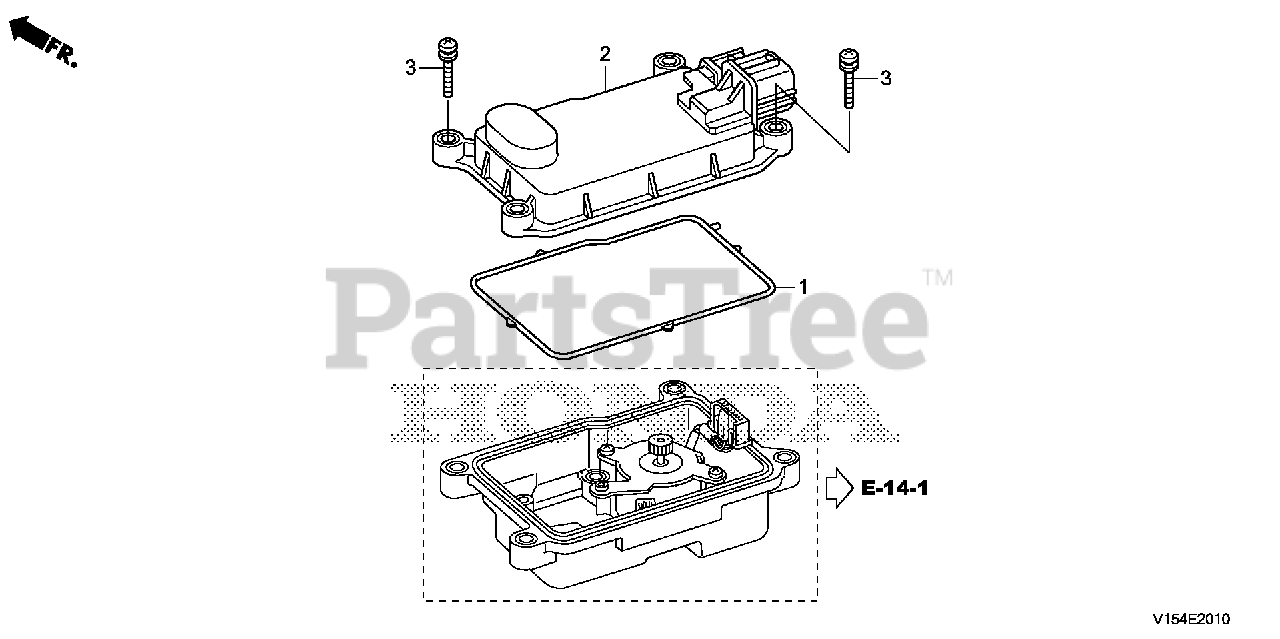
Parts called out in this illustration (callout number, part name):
1	SEAL, ELECTRONIC CONTROL UNIT COVER
2	CONTROL UNIT, ELECTRONIC
2	ECU ASSY(DATA SET
3	SCREW-WASHER (4X20)
